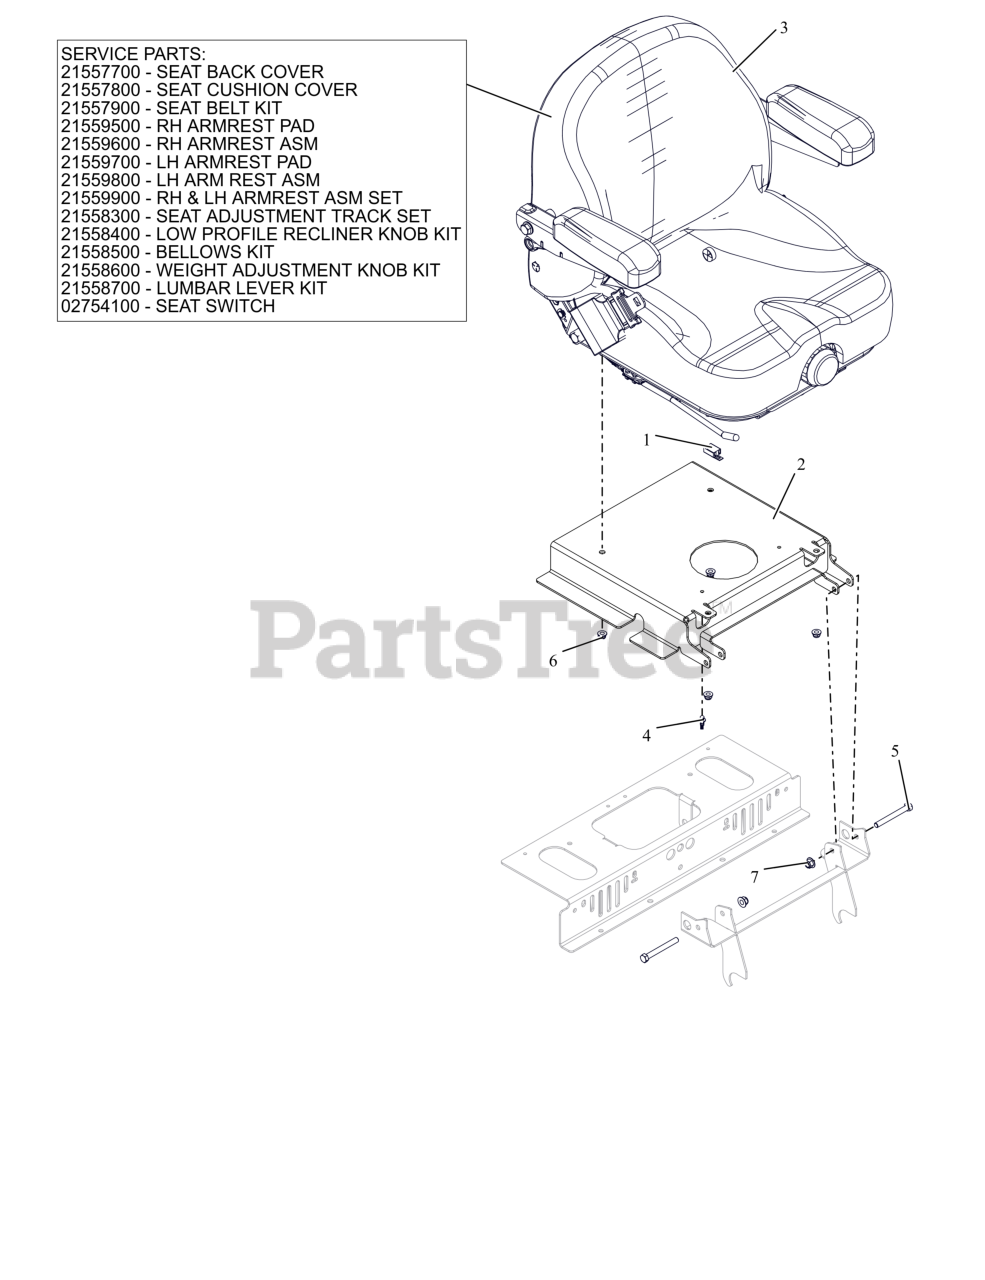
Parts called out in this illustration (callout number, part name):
1	HARNESS, PT200 SEAT ADAPTER
2	WLDMT, SEAT PLATE (RED)
3	SEAT, FULL SUSPENSION
3	COVER, SEAT BACK
3	COVER,SEAT CUSHION
3	KIT, SEAT BELT
3	PAD, RH ARMREST
3	ASM, RH ARMREST
3	PAD, LH ARMREST
3	ASM LH ARMREST
3	SET, RH & LH ARMREST ASM
3	SET, SEAT ADJUSTMENT TRACK
3	KIT, LOW PROFILE RECLINER KNOB
3	KIT, BELLOWS
3	KIT, WEIGHT ADJUSTMENT KNOB
3	KIT, LUMBAR LEVER
3	SWITCH- SNAP MTG N.O.
4	CABLE TIE W/ TREE (.25 HOLE)
5	BLT, HEX .38-16X3.25 G5 ZCC
6	NUT,NYL-FLG .31-18 GF ZCC
7	NUT,NYL-FLG .38-16 GF ZCC
